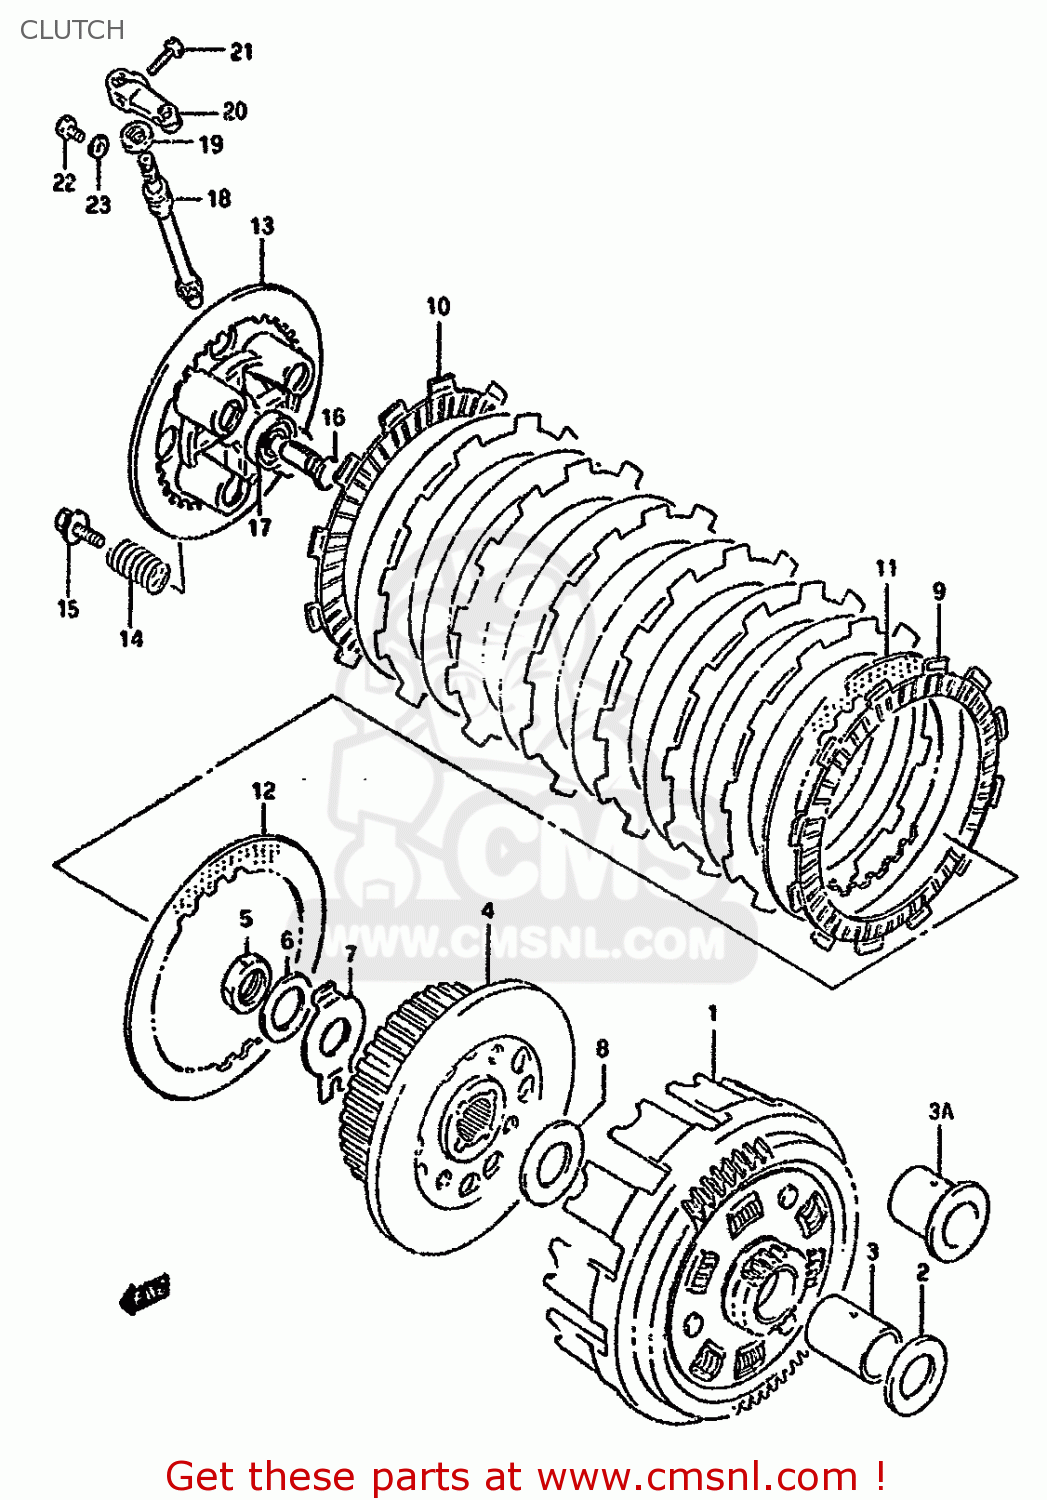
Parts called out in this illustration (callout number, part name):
1	GEAR ASSY,PRIM
2	WASHER(22X38X2)
3	SPACER
3A	SPACER,PRIMARY DRIVEN GEAR
4	HUB,CLUTCH SLEEVE
5	NUT (20MM)
6	WASHER
7	WASHER
8	WASHER(22X44X2)
9	PLATE,CLUTCH DRIVE (NAS)
10	PLATE,CLTCH DR
11	PLATE,CLUTCH DRIVEN NO.1 (NAS)
12	PLATE,CLUTCH DRIVEN (NAS)
13	DISC,CLUTCH PRESSURE
14	SPRING
15	BOLT
16	RACK,CLUTCH RELEASE
17	BEARING
18	PINION,CLUTCH RELEASE
19	SEAL,OIL(10X17X5)
20	ARM,CLUTCH RELEASE
21	BOLT
22	BOLT
23	GASKET(6.2X11X1).2 (NAS)
